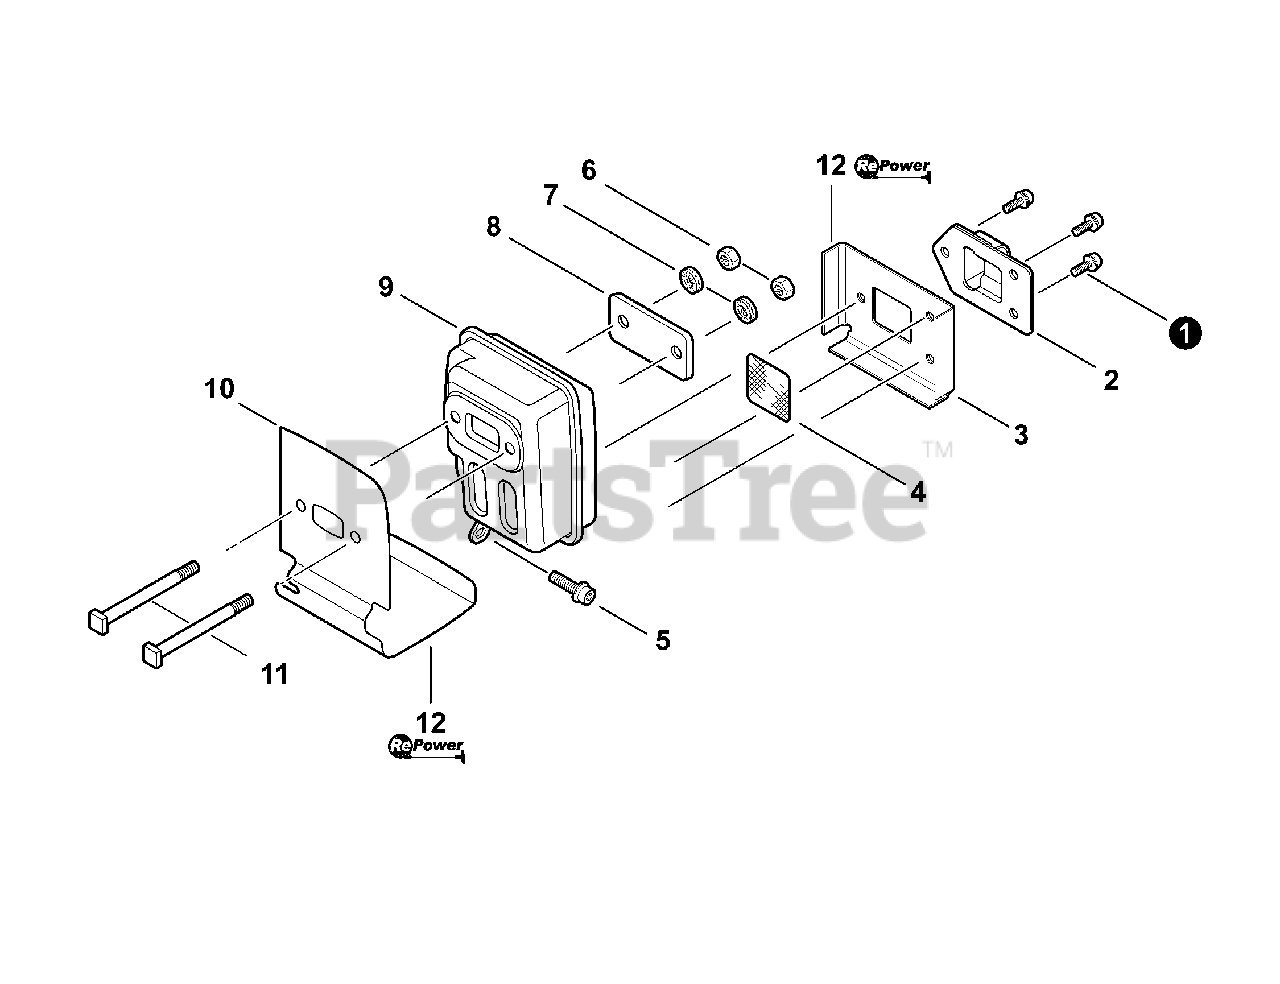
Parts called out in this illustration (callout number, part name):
1	SCREW - 4×10
2	GUIDE, EXHAUST
3	GASKET, EXHAUST
4	SCREEN, SPARK ARRESTER
5	SCREW - 5×16
7	LOCKWASHER
9	MUFFLER
10	SHIELD, EXHAUST
11	BOLT - 5
12	GASKET KIT - REPOWER
